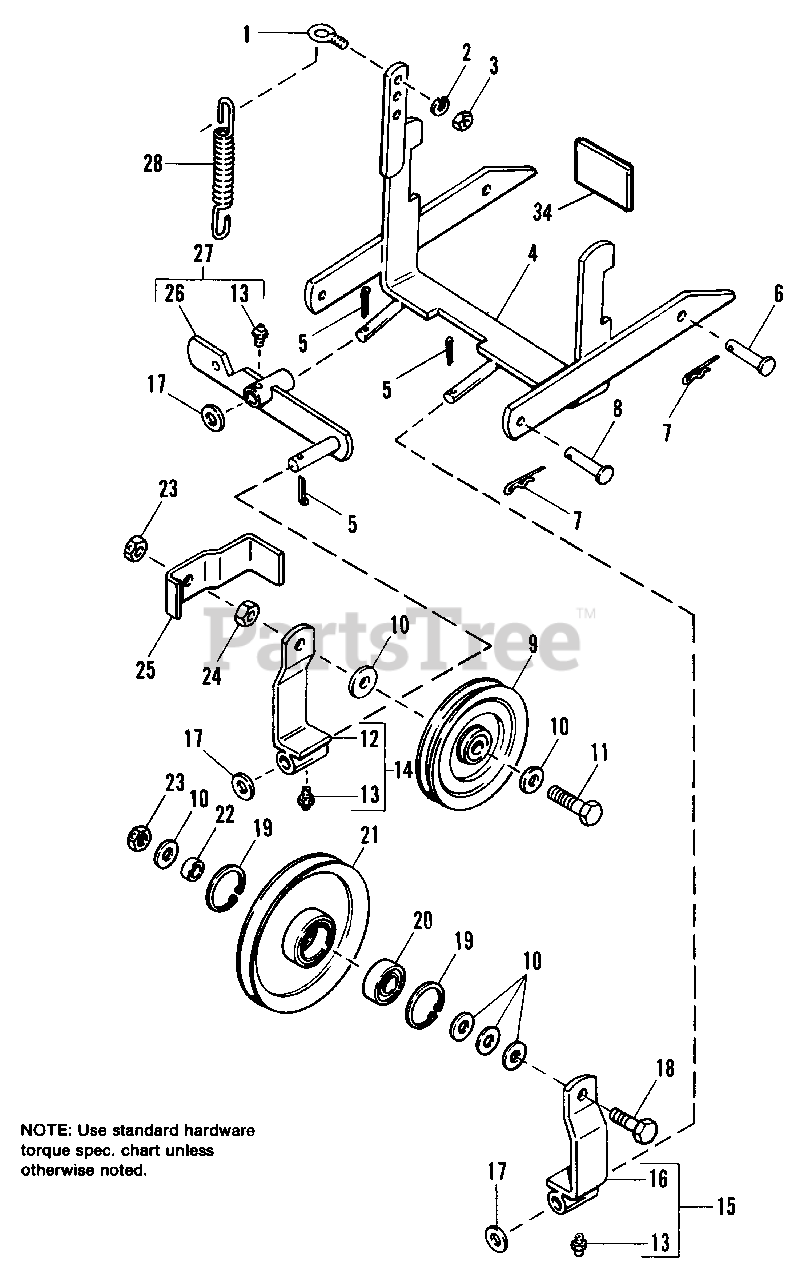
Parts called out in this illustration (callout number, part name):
2	LOCKWASHER, 1/4
3	NUT, Hex, 1/4-20
4	HITCH ASSY.
5	PIN, Cotter, 1/8 x 1
7	CLIP, Spring
8	PIN
9	PULLEY, Idler
10	WASHER, Plain, 5/16
11	CAPSCREW, Hex, 3/8-16 x 1-3/4
12	BRACKET ASSY., Idler (Incl. Ref. No. 13)
13	FITTING, Grease
14	BRACKET ASSY., Idler
15	BRACKET ASSY., Idler
18	CAPSCREW, Hex, 3/8-16 x 1-1/2
19	RING, Retaining
21	PULLEY ASSY., Idler
23	LOCKNUT, Hex, 3/8-16
24	NUT, Hex, 3/8-16
25	GUIDE, Belt
27	LEVER ASSY., Idler
